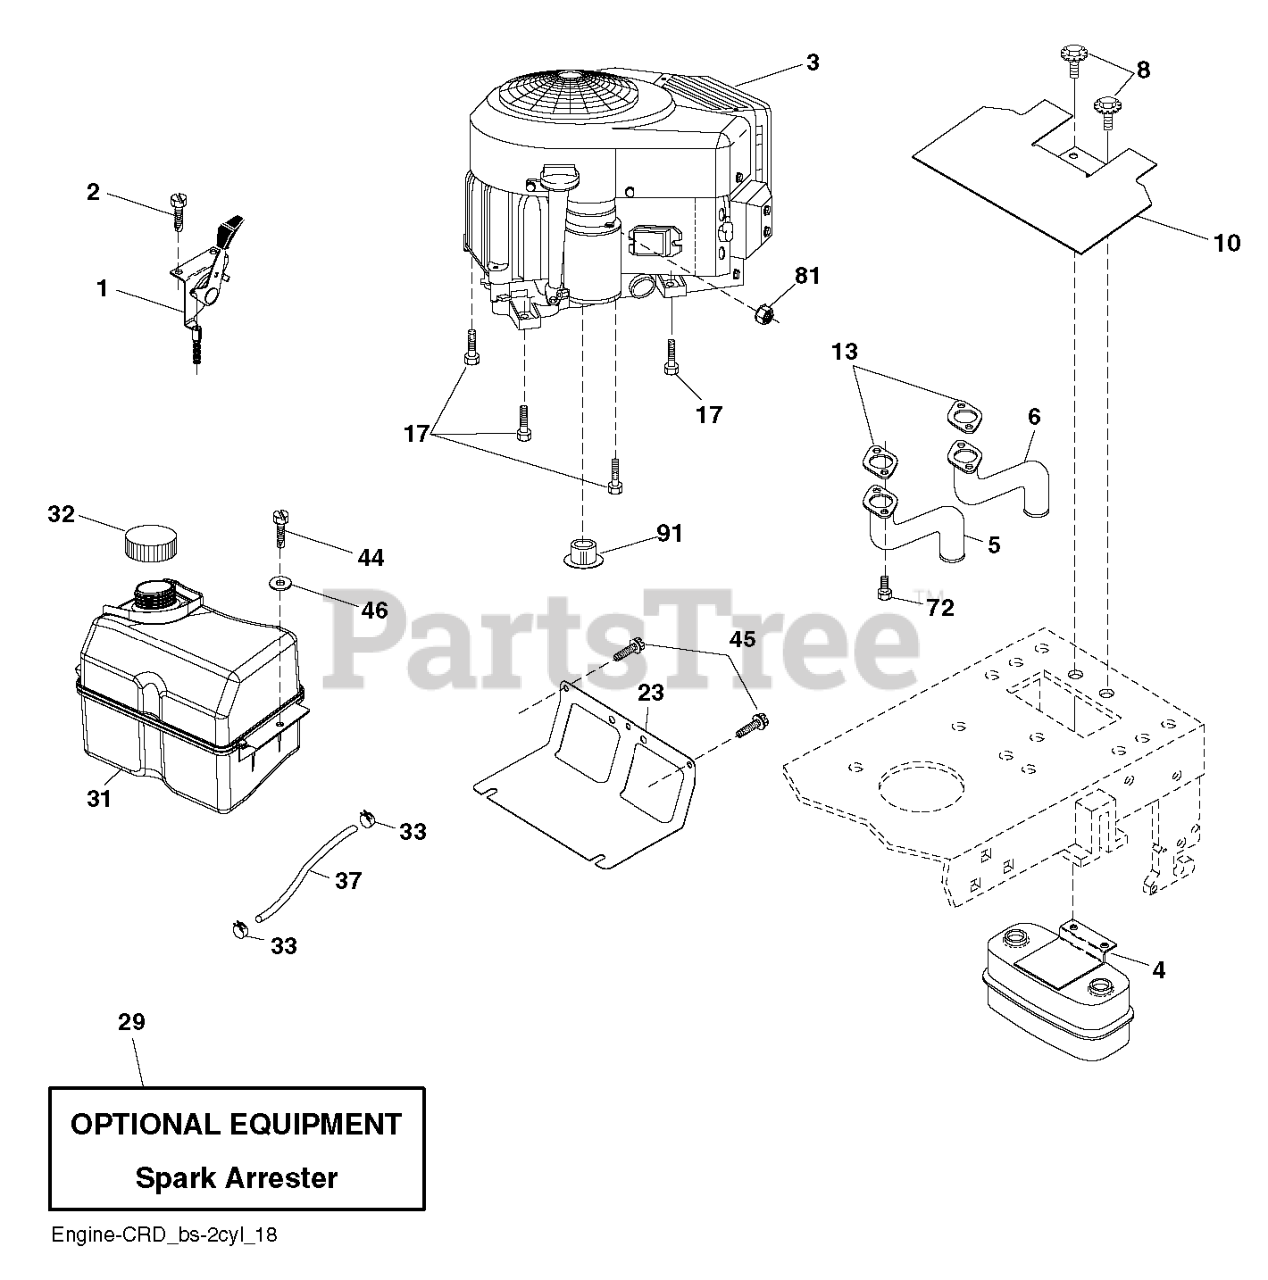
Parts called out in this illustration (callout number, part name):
1	CONTROL.TH/CK.COBRA.B&S.TWN.BK
2	SCREW.#10 X 0.750.BOS
4	MUFFLER.TWIN.CYL.LOW.TONE
5	EXHAUST.TUBE.LH.BS/TWIN
6	EXHAUST.TUBE.RH.B&S.TWIN.INTEK
8	BOLT.5/16-18UNCX3/4 W/SEMS.BLK
10	SHIELD.HEAT.MUFFLER
13	GASKET.MUFFLER
17	SCREW.3/8-16
23	SHIELD.BROWNING.PNT.GT.V2
29	KIT.SPARK ARRESTOR 794945 B&S
31	TANK.ASM.FUEL.FR.2.5GA.
32	CAP ASM.FUEL.2.25"FR.
33	HOSE CLAMP
37	LINE.FUEL.20
44	SCREW HEXWSHR 1/4-20X3/4
45	SCREW, 3/8-16X3/4
72	SCREW.SOCKET.HEAD.5/16-18
81	NUT
91	BUSHING.1.375OD
